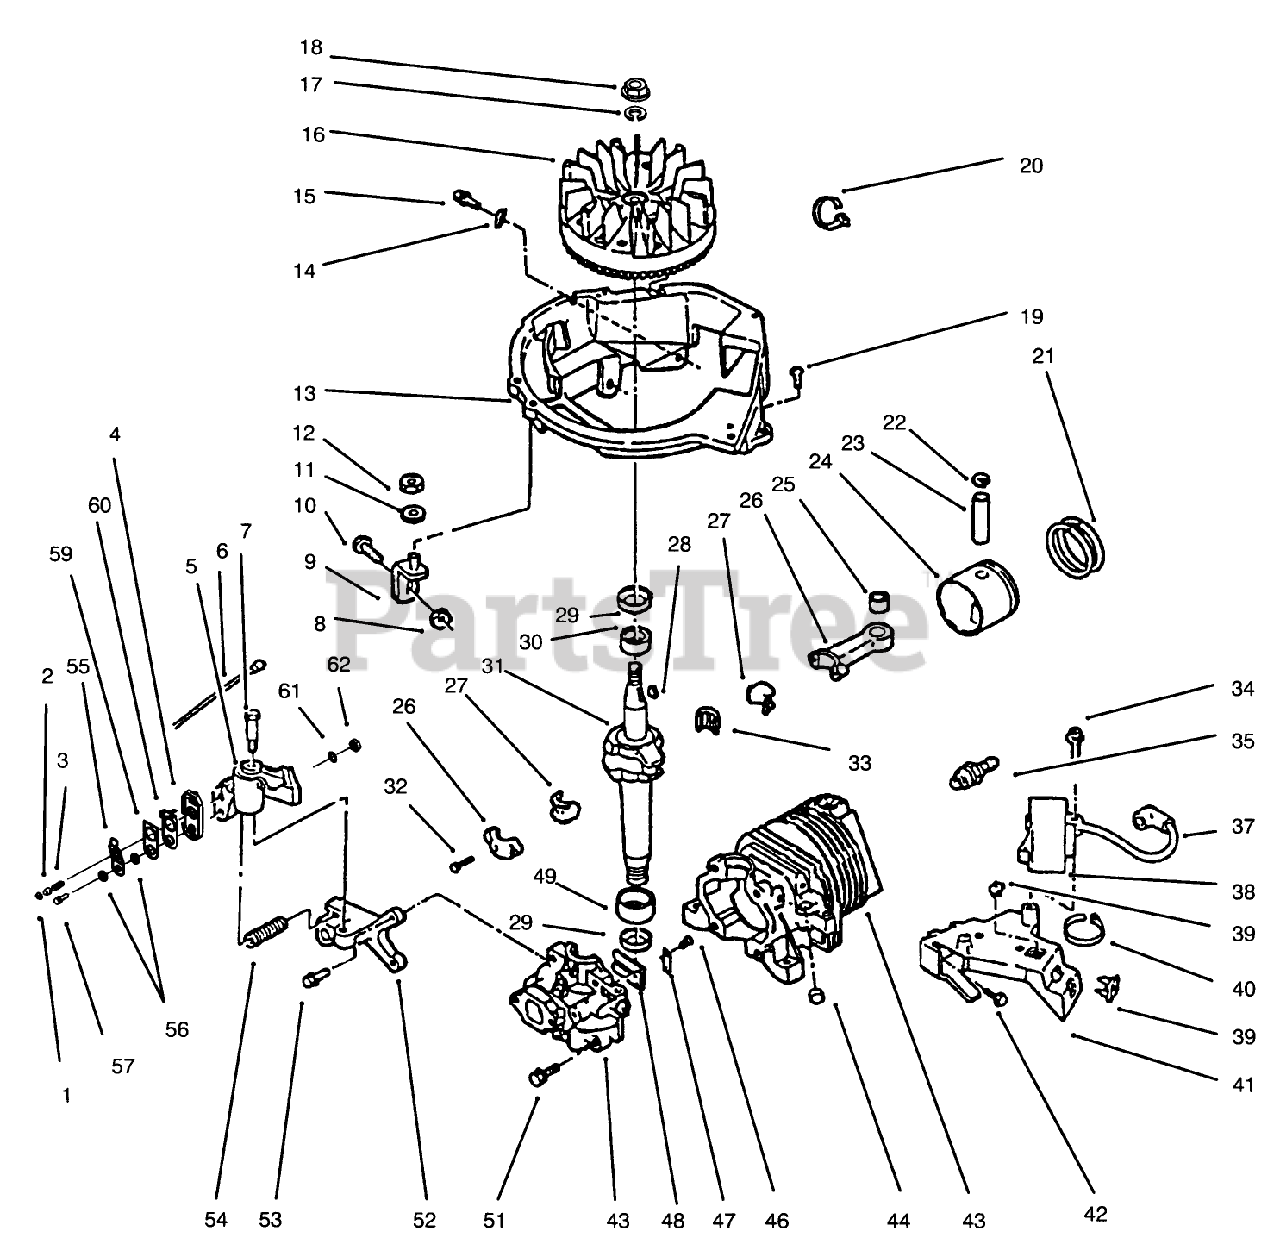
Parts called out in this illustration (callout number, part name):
1	RETAINER S
2	ACTUATOR-LEVER, BRAKE
4	CASE - SWITCH EF
6	WIRE LEAD AY F
7	SCREW-SHOULDER
8	NUT-LOCK F
9	BRACE AY F
12	LOCKNUT E
13	BASE SHROUD F
15	SCREW-SEMS
16	FLYWHEEL ASSY F
19	SCREW F
22	RING-RETAINING
25	BEARING XEV
26	CONNECTING ROD ASM
27	LINER ASM
29	SEAL-OIL
30	BEARING V
32	SCREW-HSH
33	BEARING-NEEDLE
35	SPARK PLUG
37	HT LEAD&COVER XEV
39	NUT-CLIP
40	TIE-CABLE
41	C.D. BRKT F
42	SCREW F
44	PLUG-CORE VF
46	SCREW-HH
47	PLATE-BACKUP, REED
49	BEARING V
51	SCREW-H.W.HD. F
52	BRACKET-BRAKE F
54	SPRING-BRAKE
55	SPRING-CONTACT
57	SCREW-HH
60	PLATE-CONTACT
61	WASHER-LOCK/EXT
